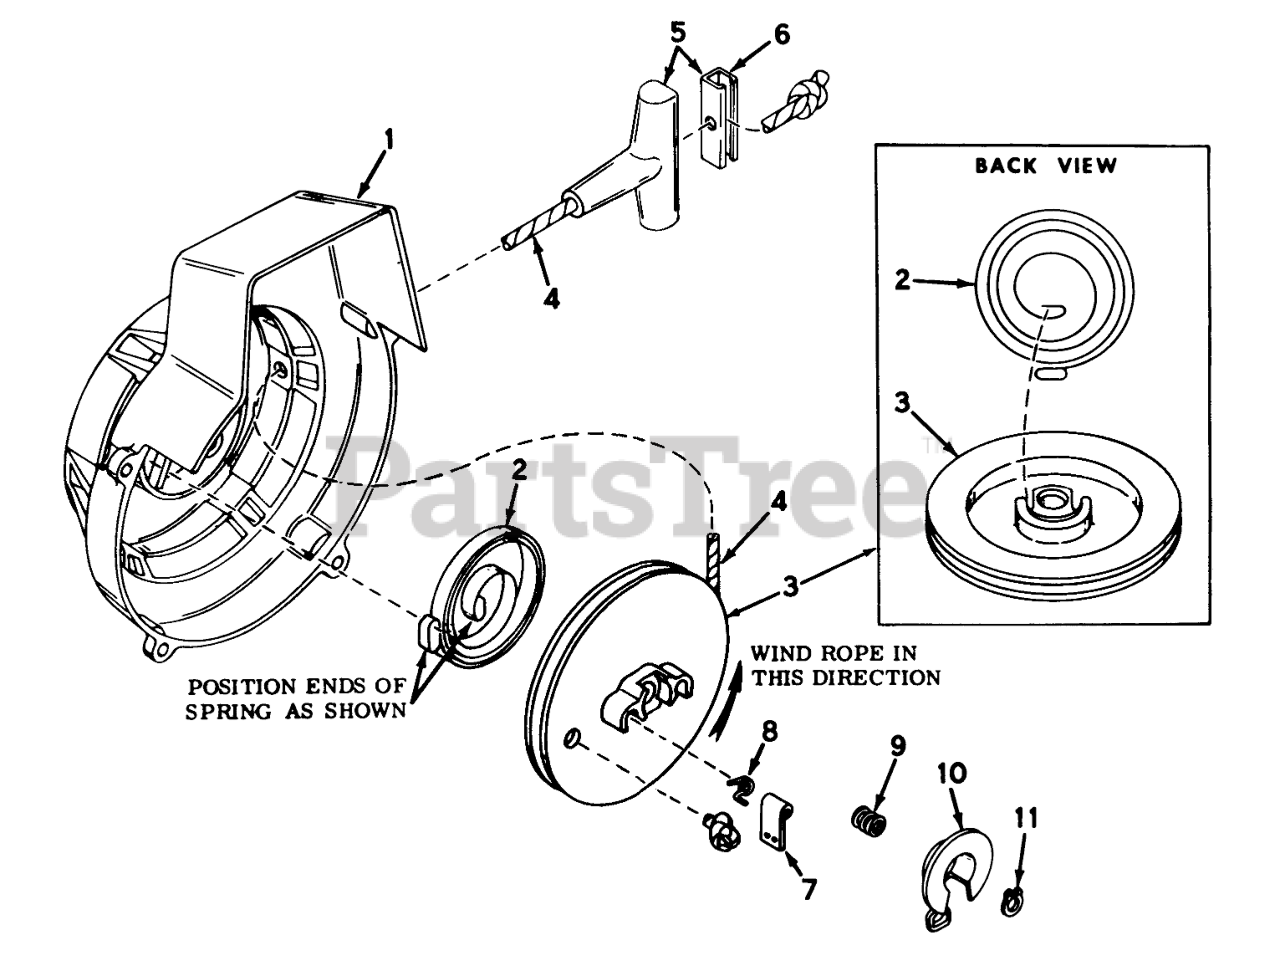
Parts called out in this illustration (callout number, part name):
1	Housing Assy., Shroud & Starter
2	Spring, Rewind
3	Pulley, Starter rope (Incl. #8)
4	Rope-Starter
5	Handle Assembly, Starter Rope (Incl . #6)
6	Insert, Handle
7	Dog, Starter
8	Retum Spring, Left Hand Wound
9	Spring, Brake
11	"E" Ring Truarc
